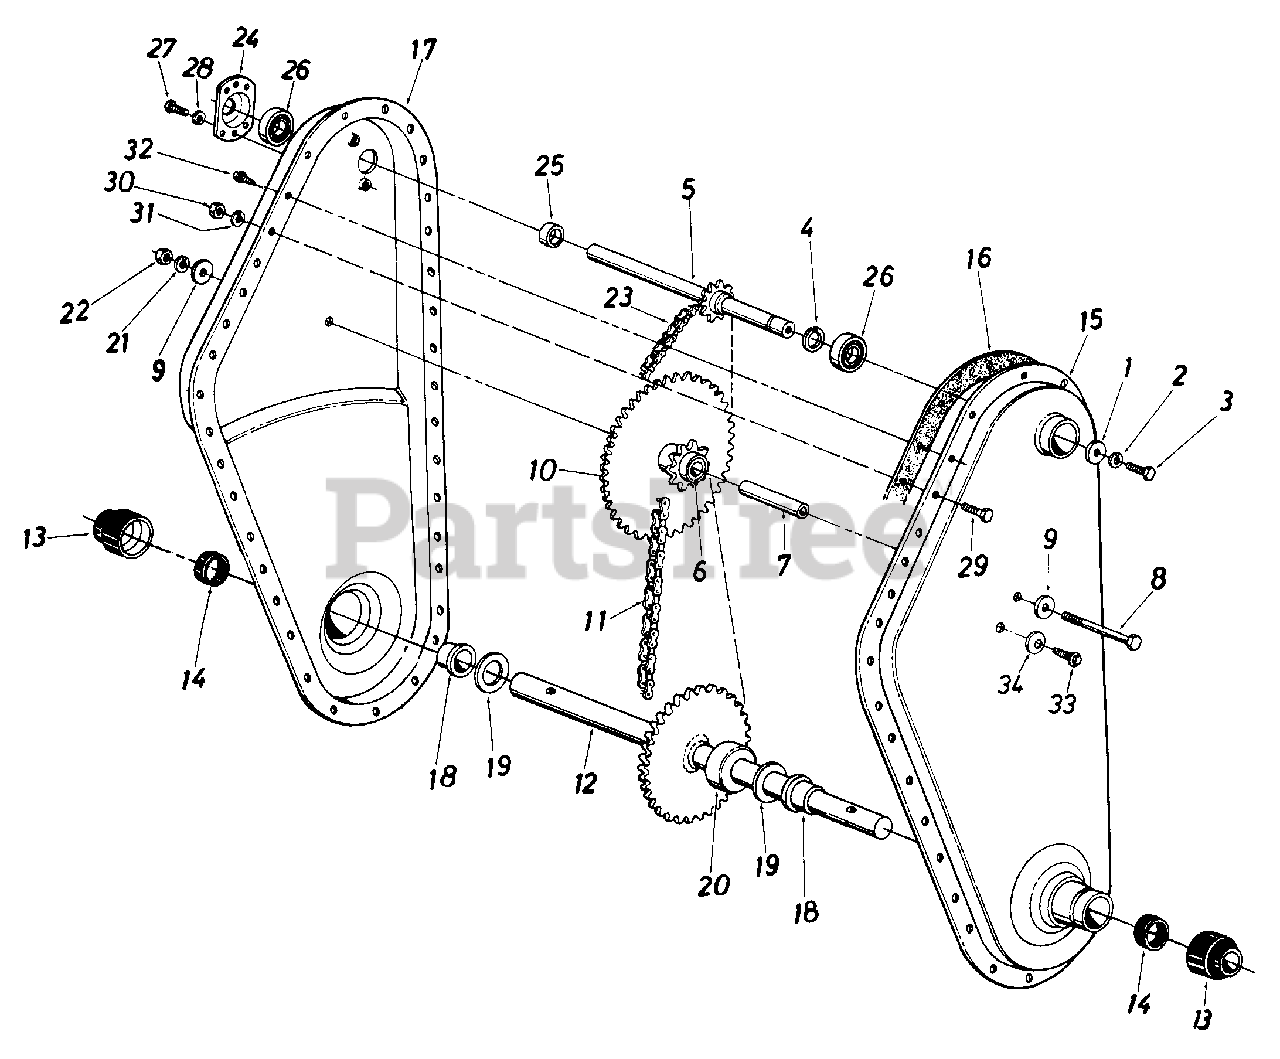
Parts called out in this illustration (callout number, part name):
1	Fl-Wash. 1/4" I.D. x .93" O.D.
2	L-Wash. 1/4" I.D.*
3	Hex Bolt 1/4-28 x .62" Lg. w/ Patch
4	External Snap Ring-5/8" Dia.
5	Input Shaft Ass'y.
6	Bearing 5/8" I.D. x 3/4" O.D. x 1.860n Lg.
7	Sprocket Hub Tubing 3/8" I.D. x 5/8" O.D. x 1.90
8	Hex Bolt 3/8-24 x 2.75" Lg.*
9	Fl-Wash. 3/8" I.D. x 1.25"
10	Sprocket Ass'y.
11	#50 Chain 5/8" Pitch x 46 Links Endless
12	Tine Shaft Ass'y.
13	Dust Cup
14	Seal Ring Single Lip
19	Fl-Thrust Wash. 1.0" I.D. x 03 Thk.
20	Step Spacer
21	L-Wash. 3/8" I.D.*
22	Hex Nut 3/8-24 Thd.*
23	#35 Chain 3/8" Pitch x 52 Links Endless
24	Bearing Housing 1.38" I.D.
25	Spacer
26	Ball Bearing .625" I.D. x 1.38" O.D. x .437
27	Hex Wash. SF-Tap Scr. 1/4-20 x 50n Lg.
28	L-Wash. 1/4" I.D.*
29	Hex Bolt 5/16-18 x 75n Lg.*
30	Hex Nut 5/16-18 Thd.*
31	L-Wash. 5/16" I.D.*
32	Hex Wash. SF-Tap Scr. 1/4-20 x .50" Lg.
33	Hex Wash. Hd. Tap Scr. 1/4-20 x 38" Lg.
34	Bell-Wash. .265" I.D. x .75"
